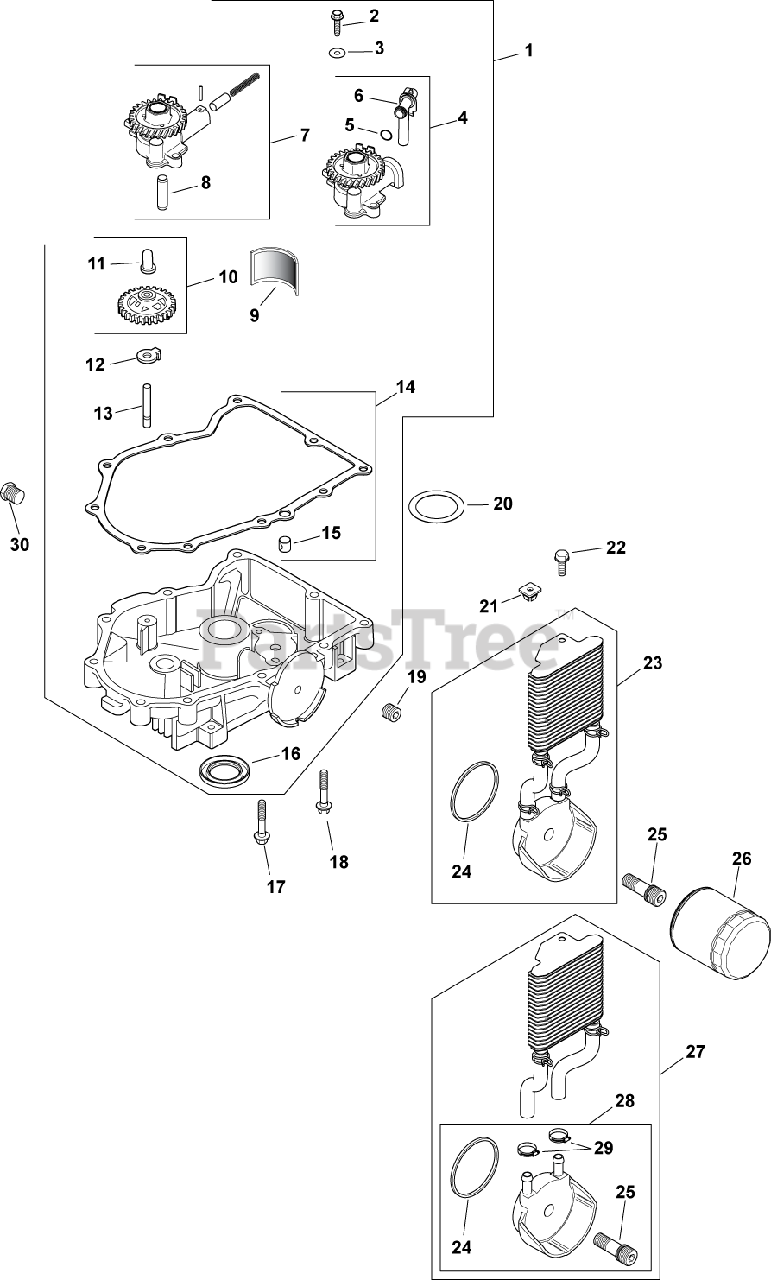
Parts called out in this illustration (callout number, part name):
1	OIL PAN W/GASKET KIT-USE 24 755 128-S
2	SCREW,FLG THD FRM M6X1.0X25-(#25086395S)
3	WASHER, FLAT 6 MM
4	PUMP ASSEMBLY, OIL-USE 24 393 53-S
5	O-RING, OIL PICK-UP
6	KIT, OIL PICK-UP TUBE
9	SCREEN, OIL
10	KIT, GOVERNOR GEAR W/PIN
11	PIN, GOVERNOR REGULATING
13	SHAFT, GOVERNOR GEAR
15	PIN, LOCATING
16	SEAL, OIL (KM)-USE 25 032 06-S
17	SCREW, HEX FLANGE -USE 24 086 17-S
18	SCREW, FLG M8X1.25X45
19	PLUG, PIPE CTSK 3/8" USE 25 139 62-S
20	SHIM, THRUST (GREEN .875MM) - DISCONTINUED
21	SCREW, TAP M6X1.7X18
22	NUT, PLASTIC (KM)-USE 25 100 37-S
23	COOLER, OIL - PHENOLIC-USE 24 594 36-S
25	NIPPLE, OIL FILTER
26	OIL FILTER
27	KIT, OIL COOLER
28	KIT,OIL FLTR ADPTR (W/DRIP LIP)
29	CLAMP, HOSE-USE 25 237 32-S
30	PLUG, HD PIPE 3/8"
2404154-S	KIT,OIL PAN GASKET USE 24 041 66-S
2408617-S	SCREW, FLG M8X1.25X45
24755128-S	KIT, OIL PAN W/GASKET USE 24 199 32-S
